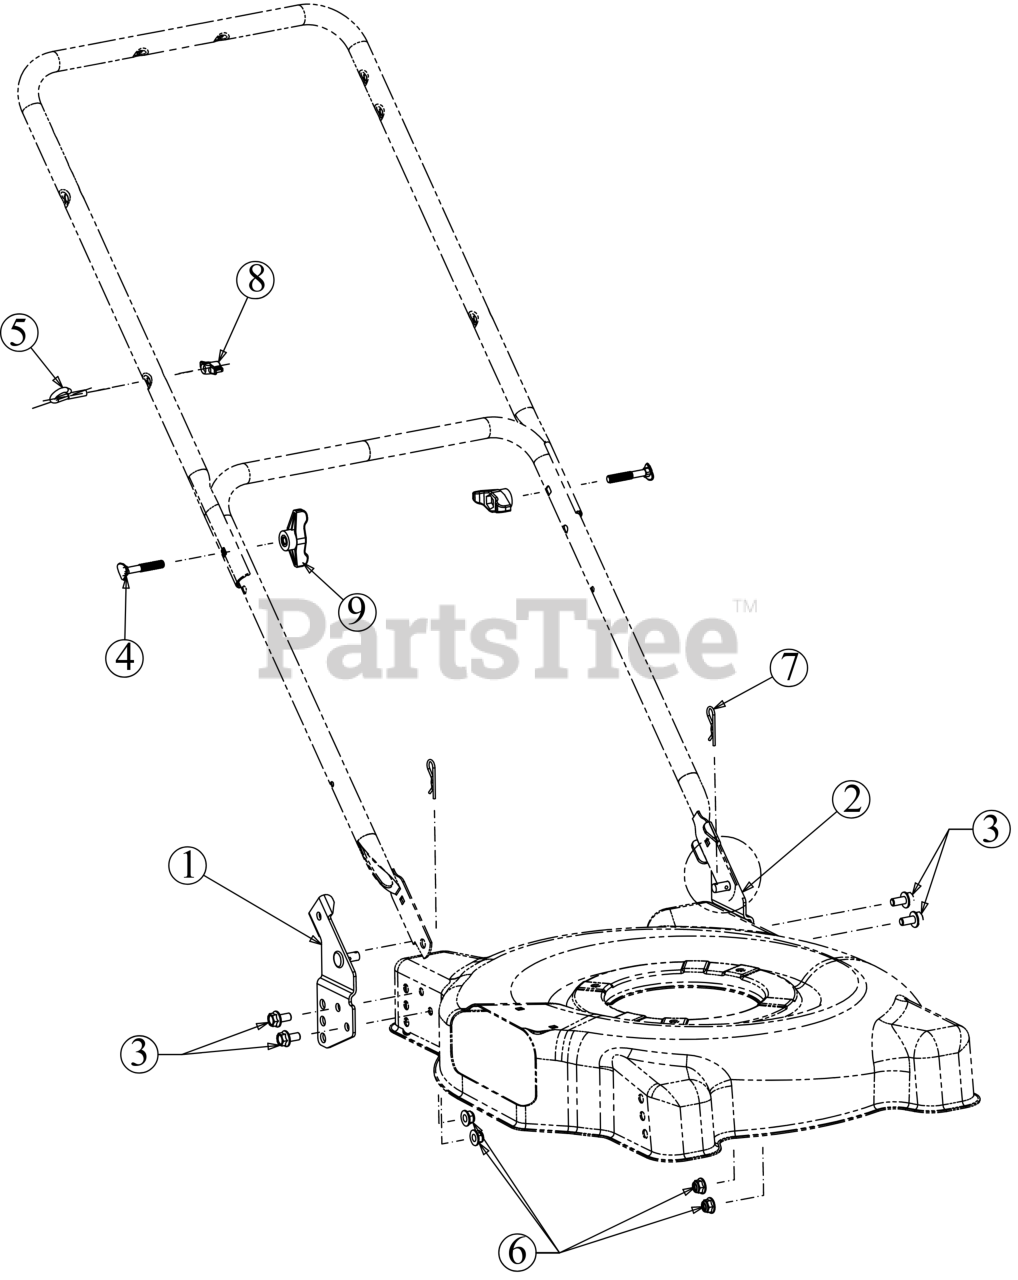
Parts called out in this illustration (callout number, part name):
1	HANDLE BRACKET ASSEMBLY (RH)
2	HANDLE BRACKET ASSEMBLY (LH)
3	SCREW 5/16-18 X .625 GR5
4	SCREW 5/16-18 X 2.0
5	EYEBOLT 1/4-20
6	FLANGE LOCK NUT 5/16-18
7	INTERNAL COTTER PIN
8	HANDLE KNOB
9	WING KNOB 5/16-18
